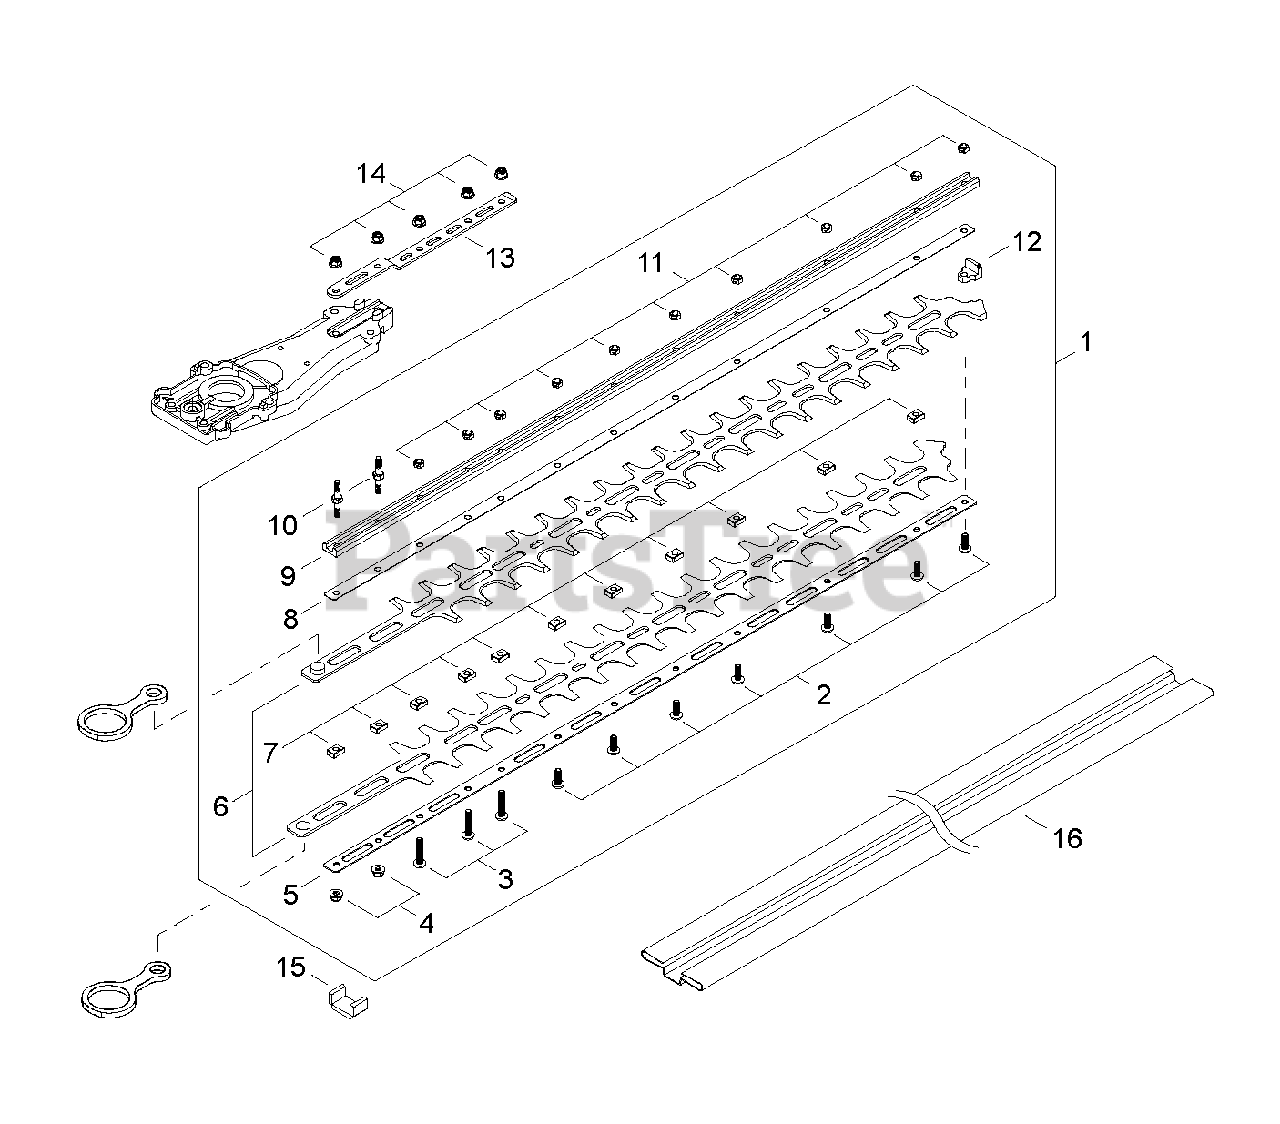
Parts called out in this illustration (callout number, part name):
1	BLADE KIT - 30" (76cm)
2	SCREW - 5X14
3	SCREW - 5X25
4	NUT - 5
5	PLATE - LOWER
6	BLADE - 30" (76cm)
7	SPACER
8	PLATE, UPPER
9	SUPPORT, BLADE - 30" (76cm)
10	STUD - 5
11	LOCKNUT - 5
12	BLOCK
13	BRACKET, CUTTER
14	NUT - 5
15	SEAL, FELT
16	COVER, BLADE - 30" (76cm)
